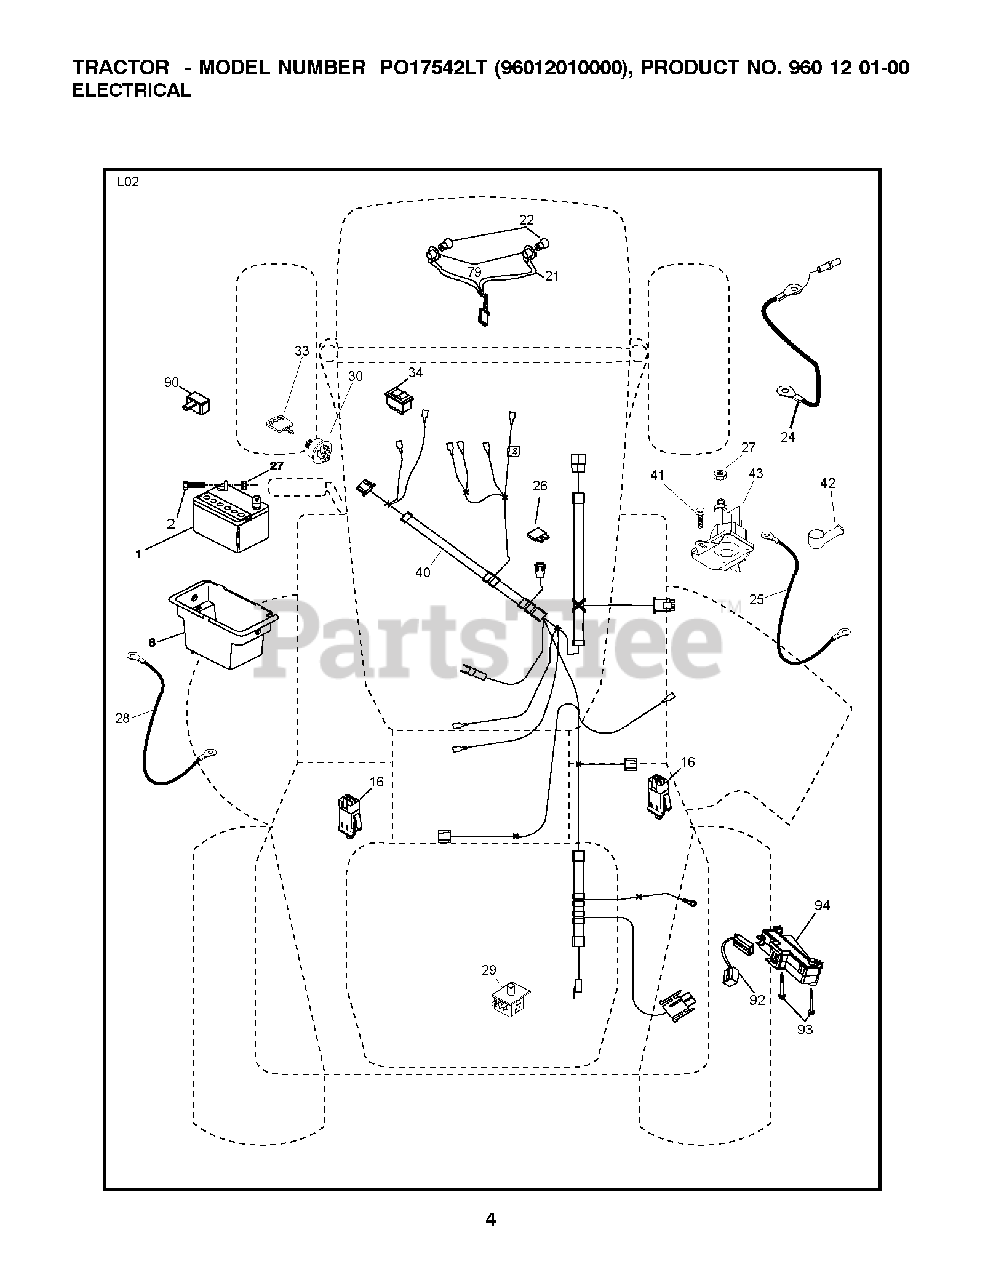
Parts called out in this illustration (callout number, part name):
1	REPL BY 532 12 38-99
2	BOLT.HEX.1/4.X.3/4.DICHROMATE
8	BOX.BATTERY.FENDER
16	SWITCH INTERLOOK PUSH-IN
21	HARNESS.W/LIGHT SOCKET
22	LIGHTBULB
24	CABLE.STARTER.6GA.11"RED
25	CABLE.GROUND.REAR.BTRY.8GA.44"
26	FUSE 20AMP
27	NUT
28	CABLE GROUND 6 GA. 12" BLACK
29	SWITCH.SEAT.DP W/RAMPS
30	SWITCH.IGN.DELTA.W.LGH.ROS
33	KEY.CHAIN.BLISTER.PACK.GEN.USA
34	SWITCH LT
40	HARNESS.IGN.CABLE.REG.
41	BOLT
42	TERMINAL COVER
43	SOLENOID.W/BRASS.PLUNGER
79	BULB HOLDER ASM.
90	COVER.TERMINAL.BATTERY
92	HARNESS.PIGTAIL.CONSLE
93	SCREW.PLASTITE
94	MODULE.REVERSE.ROS
